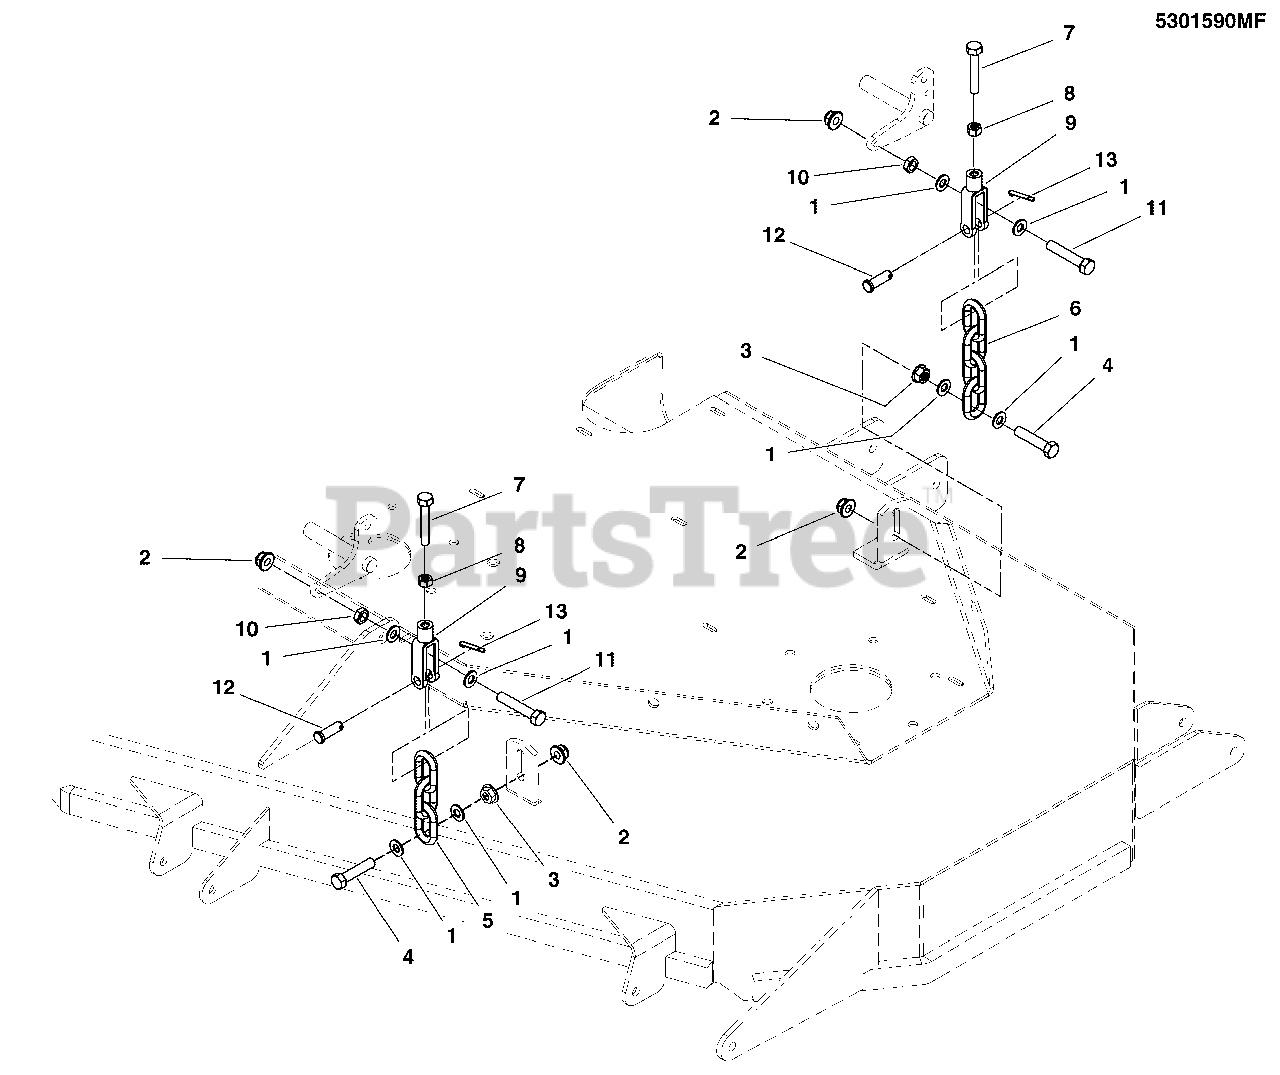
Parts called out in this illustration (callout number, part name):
1	WASHER, 3/8 SAE
2	NUT, 3/8-16 HEX NYLOCK FLANGE
3	NUT, 3/8-16 HEX SERRATED FLANGE
4	BOLT, 3/8-16 X 1-3/4 GD5
5	CHAIN, 5/16 GD30, 3 LINKS
6	CHAIN, 5/16" GD30, 4 LINKS
7	BOLT- 5/16-18 X 1-3/4 GD5 TFL
8	NUT, 5/16-18 HEX
9	CLEVIS, 5/16-18, 3/8 PIN HOLE
10	NUT, 3/8-16 HEX JAM
11	BOLT, 3/8-16 X 2 GD5 YZ
12	PIN, CLEVIS, 3/8 X 1-1/8
13	PIN, COTTER, 3/32 X 3/4
